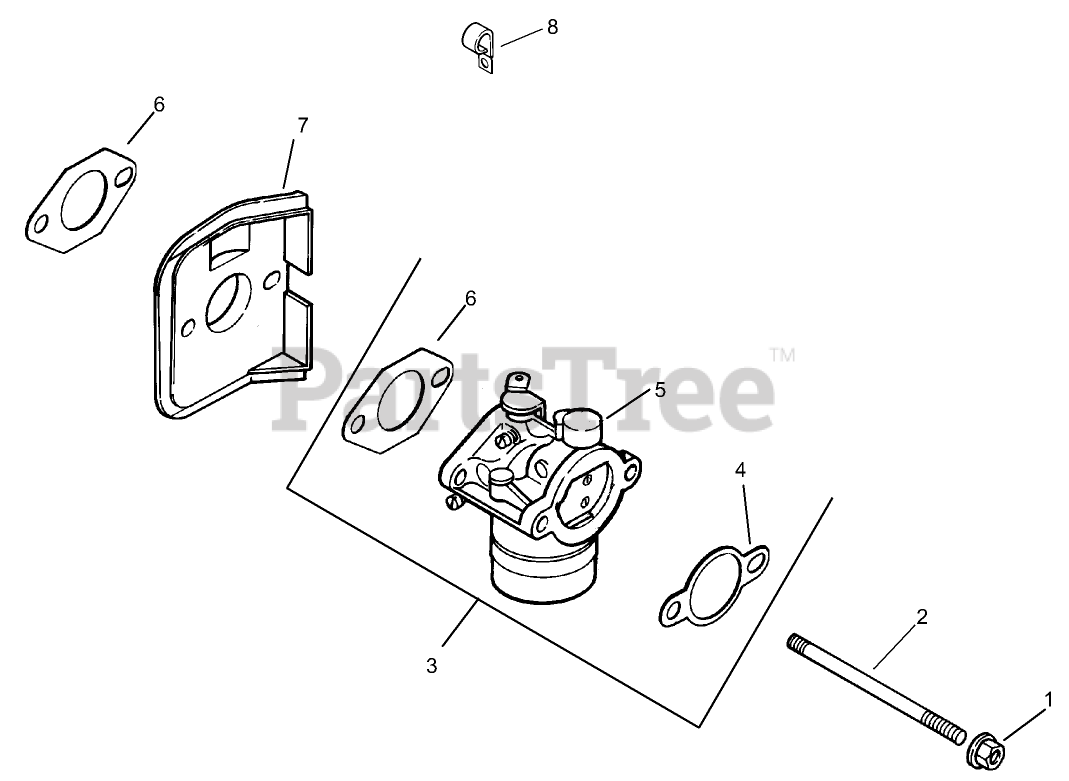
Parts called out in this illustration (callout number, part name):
1	NUT-FLANGE (M6X1.0)
2	Stud (M6x1.0x116)
3	Kit, carburetor w/gasket (Incl. Ref. #4-6 qty. 1])
4	Gasket-Base, Air Cleaner
5	Carburetor assembly (Includes: 12 75702-S, 12 757 03-S, & 12 755 92-S)(For information only not available separately)
6	Gasket-Carburetor
7	Deflector-Heat
8	CLIP-CABLE
